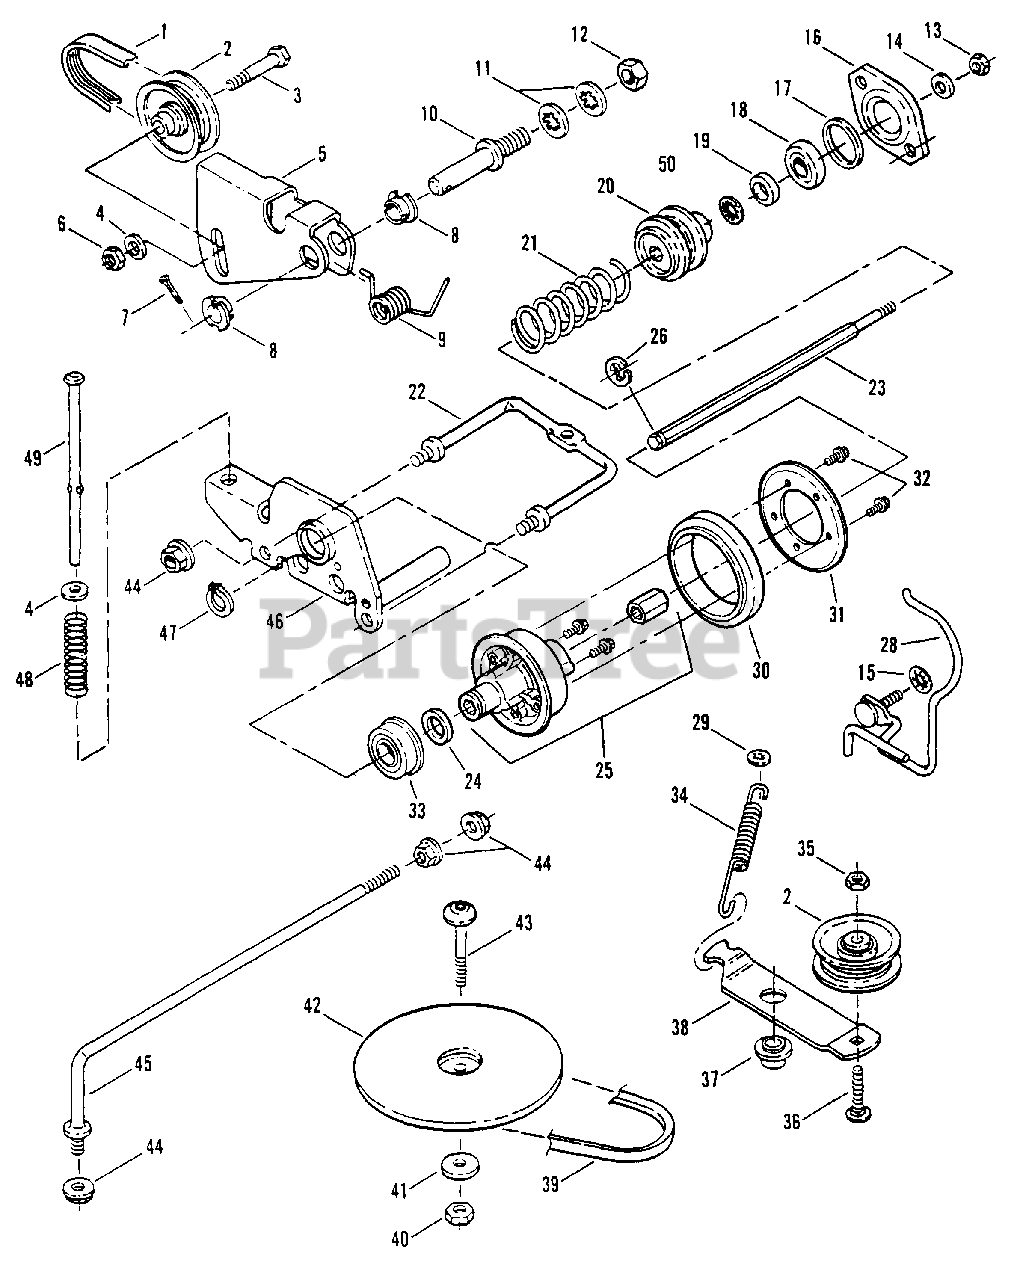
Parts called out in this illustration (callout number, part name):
1	BELT, Poly-V
2	PULLEY, Idler
3	SCREW, 1/4-28 x 1-3/8" Hex Head Cap
4	WASHER, 1/4 Flat
5	ARM, Idler
6	NUT, 1/4-20 Hex Top-Lock
7	PIN, 3/32 x 1/2" Cotter
8	BUSHING, Idler Arm
9	SPRING, Idler Arm
10	STUD, 3/8 x 2-1/8"
11	WASHER, 3/8 Internal Tooth Lock
12	NUT, 3/8-24 Hex
13	NUT, 3/8-24 Hex Center Lock
14	WASHER, Flat
15	WASHER, 1/4 Internal Tooth Lock
16	RETAINER, Bearing
17	O-RING
18	BEARING
19	SPACER
20	PULLEY
21	SPRING, Return
22	GUIDE
23	SHAFT, Hex Drive
24	WASHER, Shim
25	ASSEMBLY, Hub (Includes 11108 Bushing & 90913 Screws)
26	RING, Retaining
28	GUIDE, Belt (Front)
29	RETAINER, 5/16 Bolt
30	RING, Driven
31	PLATE, Pivot
32	SCREW, #10-24 x 1/2" Hex Washer Self-Tap (Torx)
33	BEARING
34	SPRING, Idler Arm
35	NUT, 1/4-20 Hex Jam
36	BOLT, 1/4-20 x 1-1/8" Flat Head Carriage
37	SPACER, Idler Arm
38	ARM, Idler
39	BELT, Engine Drive
40	NUT, 7/16-14 Hex Flange Center Lock
41	WASHER, Flat
42	ASSEMBLY, Drive Disc
43	SCREW, 7/16-14 x 2" Torx Head
44	NUT, 5/16-18 Hex Flange Lock
45	ROD, Guide
46	ASSEMBLY, Thrust Plate
47	RING, Retaining
48	SPRING, Plunger Rod
49	ROD, Plunger
50	RETAINER, 5/16 Bolt
